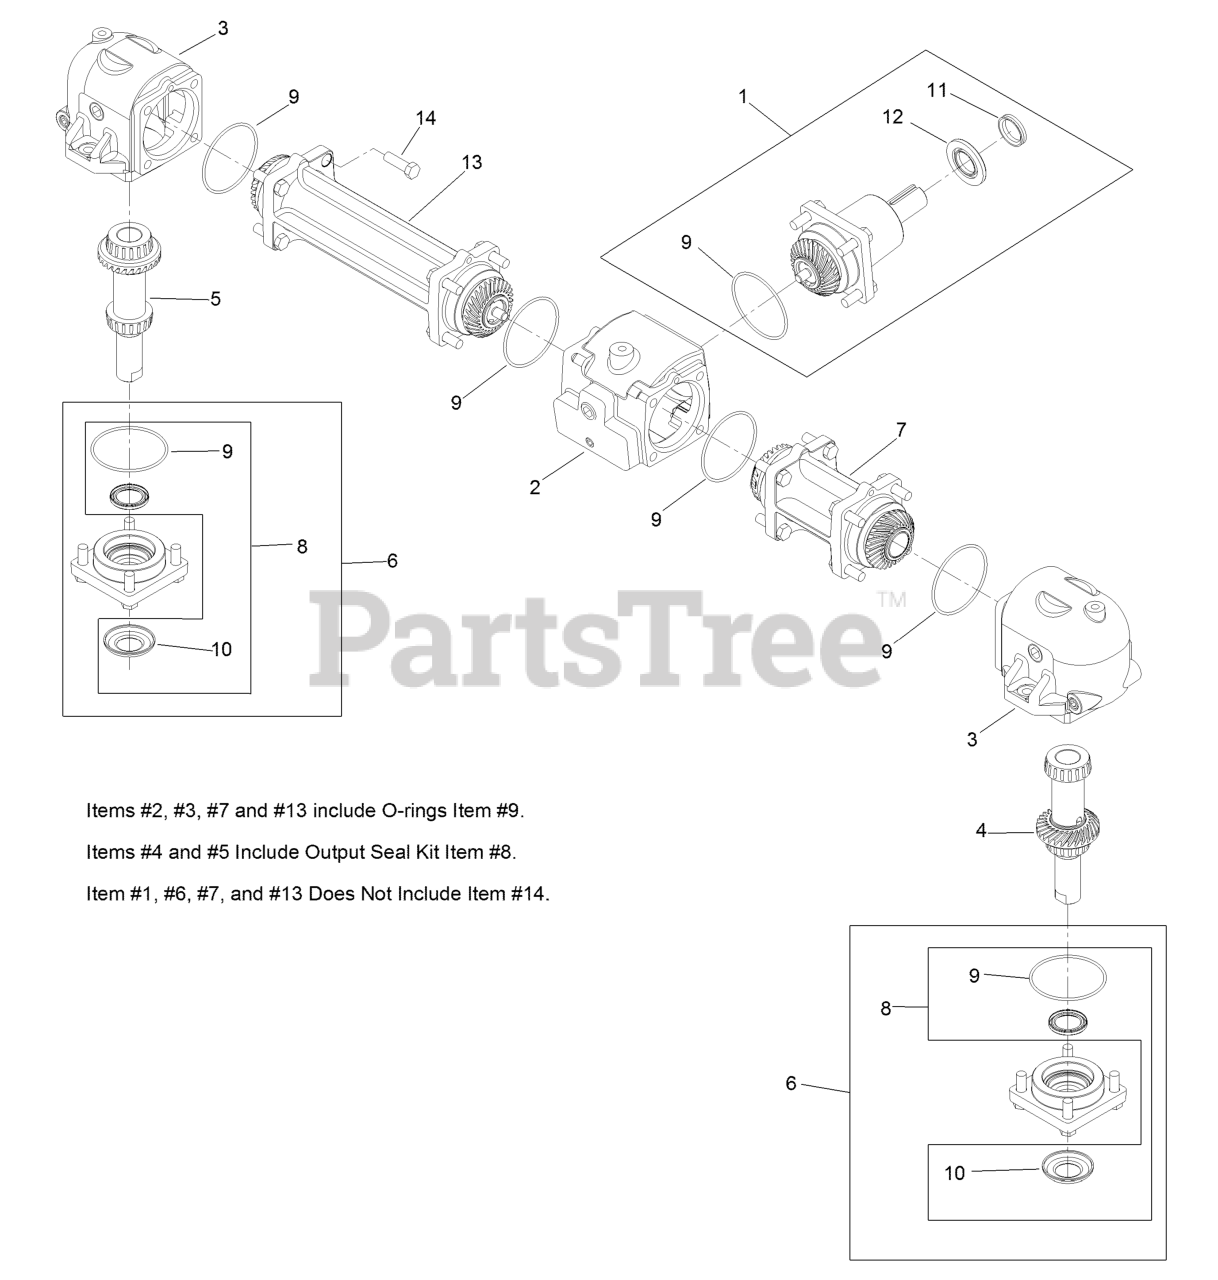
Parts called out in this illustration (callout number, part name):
1	Pinion-Input
2	Housing-Center
3	Housing-End
4	Output Shaft And Gear-LH
5	Output Shaft And Gear-RH
6	Cap-Output
7	Tube-Connector, Shor
8	Output Seal Kit
9	Seal-O-Ring
10	Washer-Cupped
11	Seal-V-Ring
12	Seal-Input
13	Connector-Tube, Long
14	Bolt-Blade
